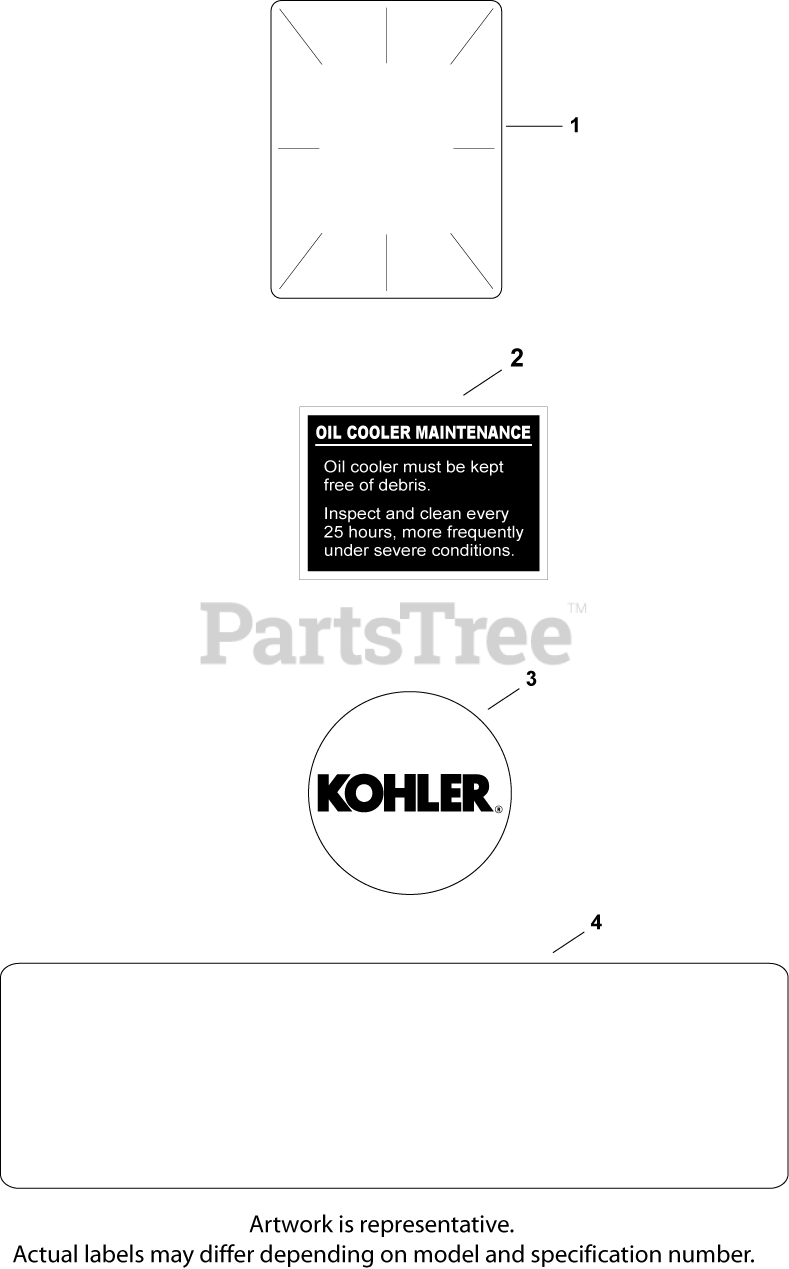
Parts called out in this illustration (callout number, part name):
1	DECAL, CLEAR LAMINATE USE 25 113 70-S
2	DECAL, OIL COOLER - (#DSC)
3	DECAL, GRASS SCREEN USE 24 113 499-S
4	DECAL, 20 HP - DISCONTINUED
